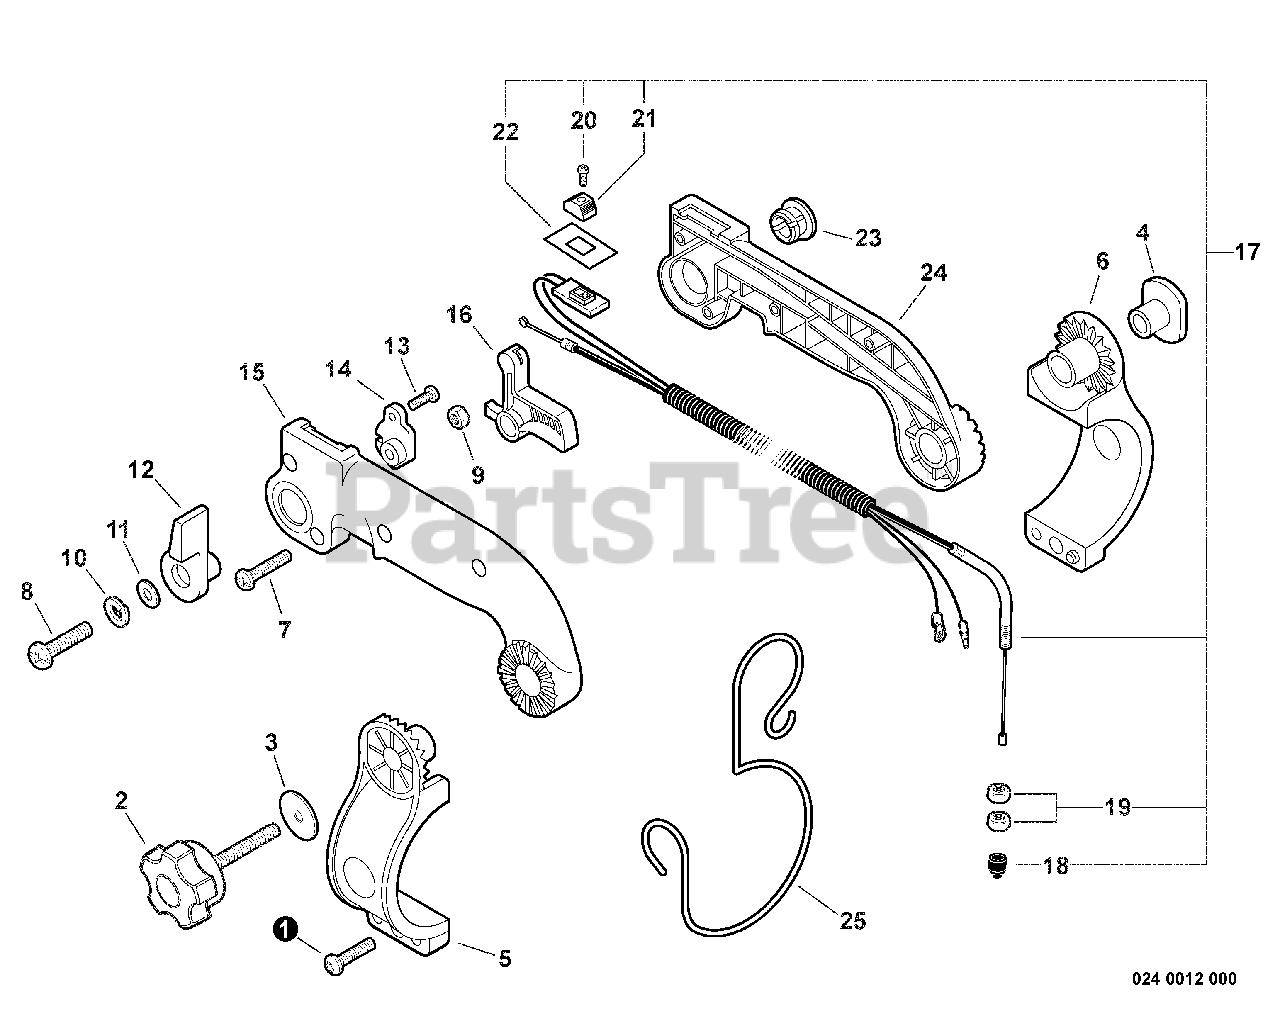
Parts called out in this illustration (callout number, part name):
1	SCREW TAPPING 5×20
2	KNOB, SCREW
5	BRACKET, HANDLE - LEFT
6	BRACKET, HANDLE - RIGHT
7	SCREW 4×22
8	SCREW 6×20
9	NUT, HEX M6
10	WASHER, SPRING 6
11	WASHER 6.5×13×1
12	CONTROL, THROTTLE
13	SCREW 4×10
14	BRACKET, THROTTLE
15	CONTROL HANDLE - LEFT
16	TRIGGER, THROTTLE
17	CABLE ASSY, CONTROL
18	CAP, DUST
19	NUT 6 MM
20	SCREW 3×10
21	KNOB, SWITCH - ORANGE
22	LABEL, SWITCH
24	CONTROL HANDLE - RIGHT
